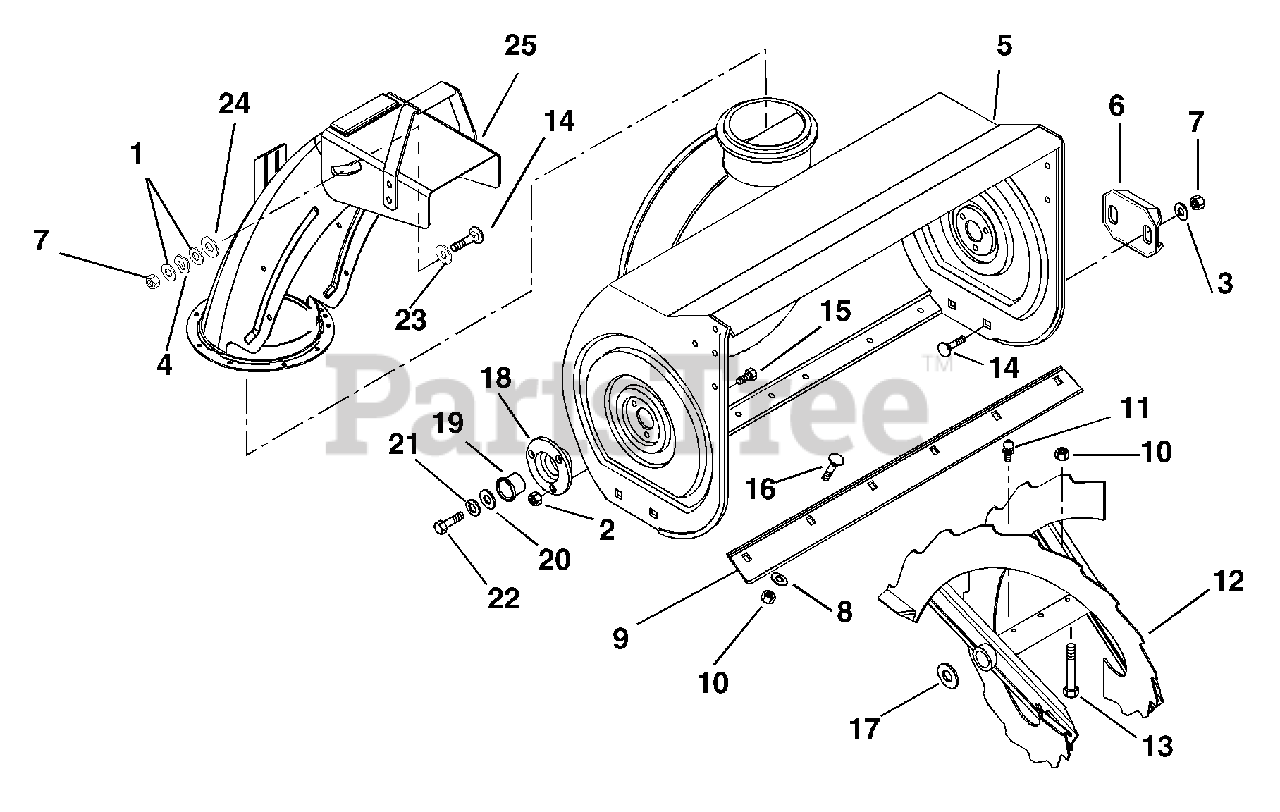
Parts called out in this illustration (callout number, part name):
1	@WSHR-FL-STL.406X.812X.065 YWZ
2	@NUT-SPNLK-FLG .25-20 YWZC
3	@WSHR-FL-STL.438X1.00X.083 YWZ
4	WAVE WASHER .390X.655X.110
5	HOUSING, 24" BLOWER W/DECAL
6	SKID SHOE, REVERSIBLE - ORANGE
7	@NUT-LK-CTR .38-16 YWZC
8	@WSHR-FL-STL.38X.875X.083 YWZC
9	SCRAPER, BLADE 24"
10	@NUT-LK-CTR .31-18 YWZC
11	FTG-LUBE .25-28X.256 YWZC
12	RAKE, RIGHT-24"(1ID X 14.75OD)
13	SHEAR BOLT SERVICE ASSEMBLY
14	BLT-RHHDSQSHNK .38-16X.75 G2YZ
15	BLT-SERNK SL .25-20X.50 YWZC
16	@BLT-RHDSSQNK .31-18X.62 G5YZ
17	WSHR-FL-STL 1.010X1.505X.062YZ
18	BEARING SUPPORT
19	BSHG-FLG 1.000X1.12X.62X1.50BR
20	WSHR-FL-STL.511X1.441X.125 YWZ
21	WSHR-LK .500X.151 HVY YWZC
22	@BLT-HEX .50-13X1.00 GR5 YWZC
23	WSHR-FL-STL .52X.827X.062 YWZC
24	WSHR-PLASTIC .390X.875X.062
25	CHUTE, DISCHARGE W/O REMOTE
